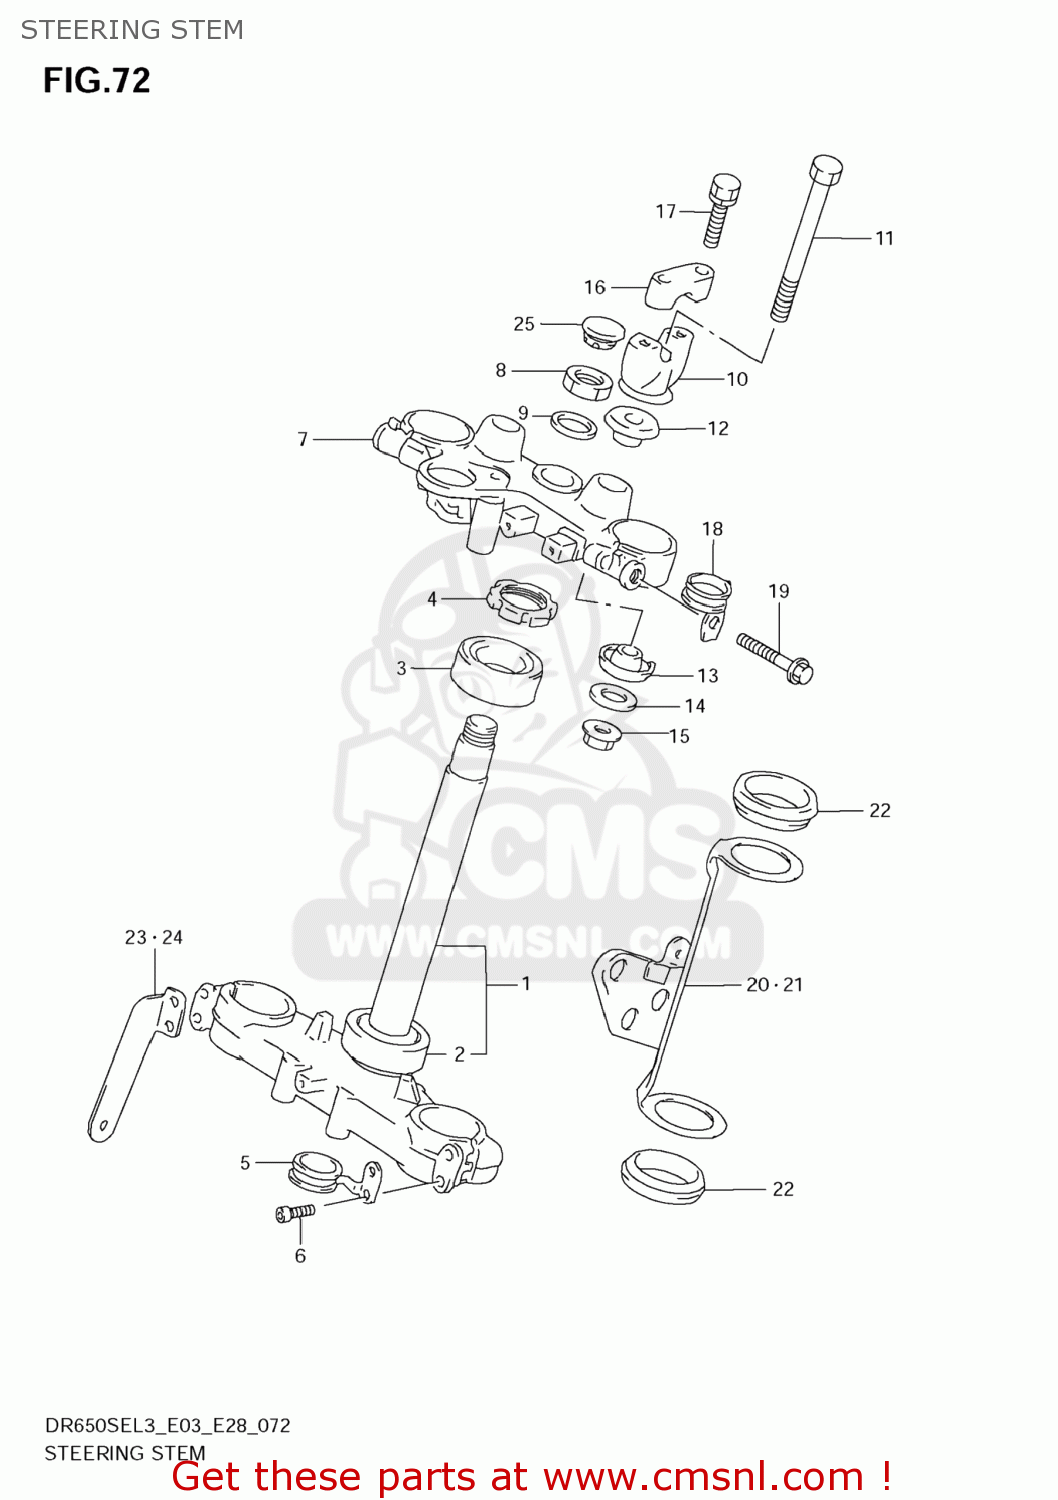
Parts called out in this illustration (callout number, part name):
1	STEM,STEERING
2	BEARING(30X52X16)
3	BEARING(30X52X16)
4	NUT,STEERING
5	GUIDE,BRAKE HOSE LWR
6	BOLT
7	HEAD,STEERING STEM
8	NUT
9	WASHER,STEM HEAD(24.5X34X1.6)
10	HOLDER,HANDLE LWR
11	BOLT
12	DAMPER,UPR
13	DAMPER,LWR
14	WASHER(10.5X28X2.3)
15	NUT
16	HOLDER,HANDLE(BLACK)
17	BOLT
18	CLIP
19	BOLT
20	COVER,FORK,R
21	COVER,FORK,L
22	DAMPER,HEADLAMP HSG BRACKET
23	BRACKET,FR SIDE REFLECTOR,R
24	BRACKET,FR SIDE REFLECTOR,L
25	CAP(OD:20)
